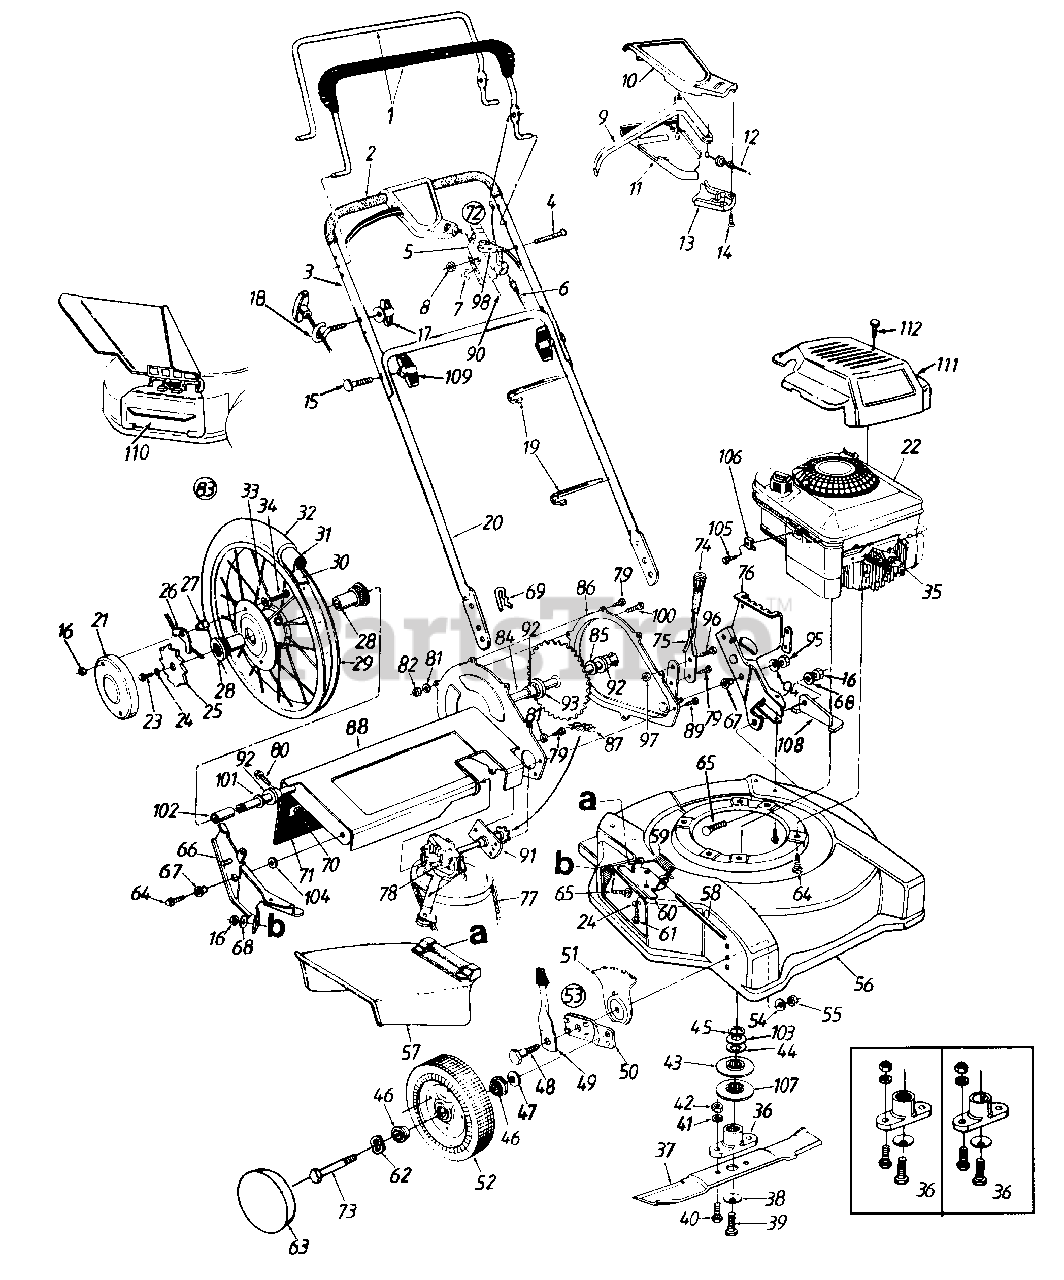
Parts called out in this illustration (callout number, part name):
1	Control Handle Ass'y.
2	Foam Grip
4	Oval C-Sunk Scr.
5	Throttle Body
6	Control Cable-39" Lg.
7	Spring Wash. .66" I.D.
8	Hex L-Nut 1/4-20 Thd.
9	Control Lever
10	Control Cover Half-Upper
11	Control Cover Half-Lower
12	Self-Properlled Cable-48" Lg.
13	Cable Mounting Cap
14	FL-"C" Sunk Hd. Tap Scr. #10 x .75" Lg.
15	Curved hd. Bolt 5/16-18 x 2" Lg.
16	Hex Nut 5/16-18 Thd.
17	Handle Knob 1/4-20 Thd.
18	Rope Guide
19	Cable Tie
21	Wheel Cover
22	Engine
23	Hex Bolt 1/4-20 x .75" Lg. (Gr. 5)
24	Bell-Wash. 1/4" I.D.
25	Wheel Ratchet
26	Pawl and Spring Ass'y.
27	Special Hex Nut 5/16-18 Thd.
28	Flange Bearing .63" I.D.
29	Rim Ass'y. Only 16" x 2.1"
30	Rimstrip 16" x 2.12"
31	Inner Tube 16" x 2.12"
32	Chevron Tire 16" x 2.125"
33	Intern. L-Wash. 5/16" I.D.
34	Hex Bolt 5/16-18 x 1.0" (Gr. 5)
35	Spark Plug Boot
36	Blade Adapter Kit
37	22" Blade
38	Bell-Wash. .46" I.D.
39	Hex Bolt 7/16-20 x 1.5" Lg.
40	Hex Bolt 3/8-24 x 1" Lg.
41	L-Wash. 3/8" I.D.
42	Hex Nut 3/8-24 Thd.
43	Pulley Half
44	Bell-Wash. 1.01" I.D.
45	Crankshaft Spacer
46	Ball Bearing 1/2" I.D.
47	Bell-Wash. .38" I.D.
48	Shld. Bolt .5"
49	Spring Lever Ass'y. w/Knob
51	Height Adj. Plate
52	Wheel Ass'y. Comp.
53	height Adj. Ass'y. Comp.-R.H.
54	Bell-Wash. .39" I.D. x 1.38"
55	Hex Nut 3/8-16 Thd.
58	Hinge Pin
59	Torsion Spring
60	Adapter Plate
61	Hex TT-Tap Scr. 1/4-20 x .5"
62	Wave Wash. .51" I.D. x .78
63	Hub Cap Gray (5-1/2" Dia.)
63	Hub Cap Gray (3-1/2" Dia.)
63	Hub Cap Gray (4-1/4" Dia.)
63	Hub Cap Black (4-1/4" Dia.)
64	Hex TT-Tap Scr. 3/8-16 x 1"
65	Carriage Bolt 5/16-18 x .62" Lg.
66	Handle Brkt. Ass'y.-R.H.
67	Shld. Spacer .5" x .10"
68	Bell-Wash. 5/16" I.D.
69	Intern. Cotter Pin 5/16" Dia.
70	Retaining Strip
71	Rear Flap
72	Throttle Box Comp.
73	Front Axle Bolt
75	Height Adjustment Lever
78	Transmission Comp.
79	Hex B-Tap Scr. 1/4 x .38" Lg.
80	hex AB-Tap Scr. 1/4 x .62" Lg.
81	L-Wash. 1/4" I.D.
82	Hex Nut 1/4-20 Thd.
83	Wheel Ass'y. Comp.
84	Sprocket and Axle Ass'y.
85	FL-Wash. .635" I.D. x 1.0" O.D.
90	Throttle Cable
92	Hex Flange Brg. .631" I.D.
93	Spacer .63" I.D. x 1.25"
94	FL-Wash. .385" I.D. x 87" O.D.
95	Hex L-Nut 3/8-25 Thd.
96	Hex Bolt 3/8-16 x .62" Lg.
97	Flanged L-Nut 3/8-17 Thd.
98	Throttle Lever
100	Hex Bolt 1/4-20 x .5" Lg.
101	FL-Wash. .632" I.D. x .943"
102	Spacer .628" I.D. x .875"
103	Bell-Wash. 1.01" I.D.
104	FL-Wash. .38" I.D. x 1. O.D.
105	Wash. Hd. Scr. #10-32 x .62" Lg. (B&S)
106	Casing Clamp (B&S)
107	Lower Pulley Half
108	Deck Bracket
109	Hand Knob
110	Mulching Baffle
111	XTE Black Shroud
112	Hi-Lo Scr. #10 x 1.25" Lg.
